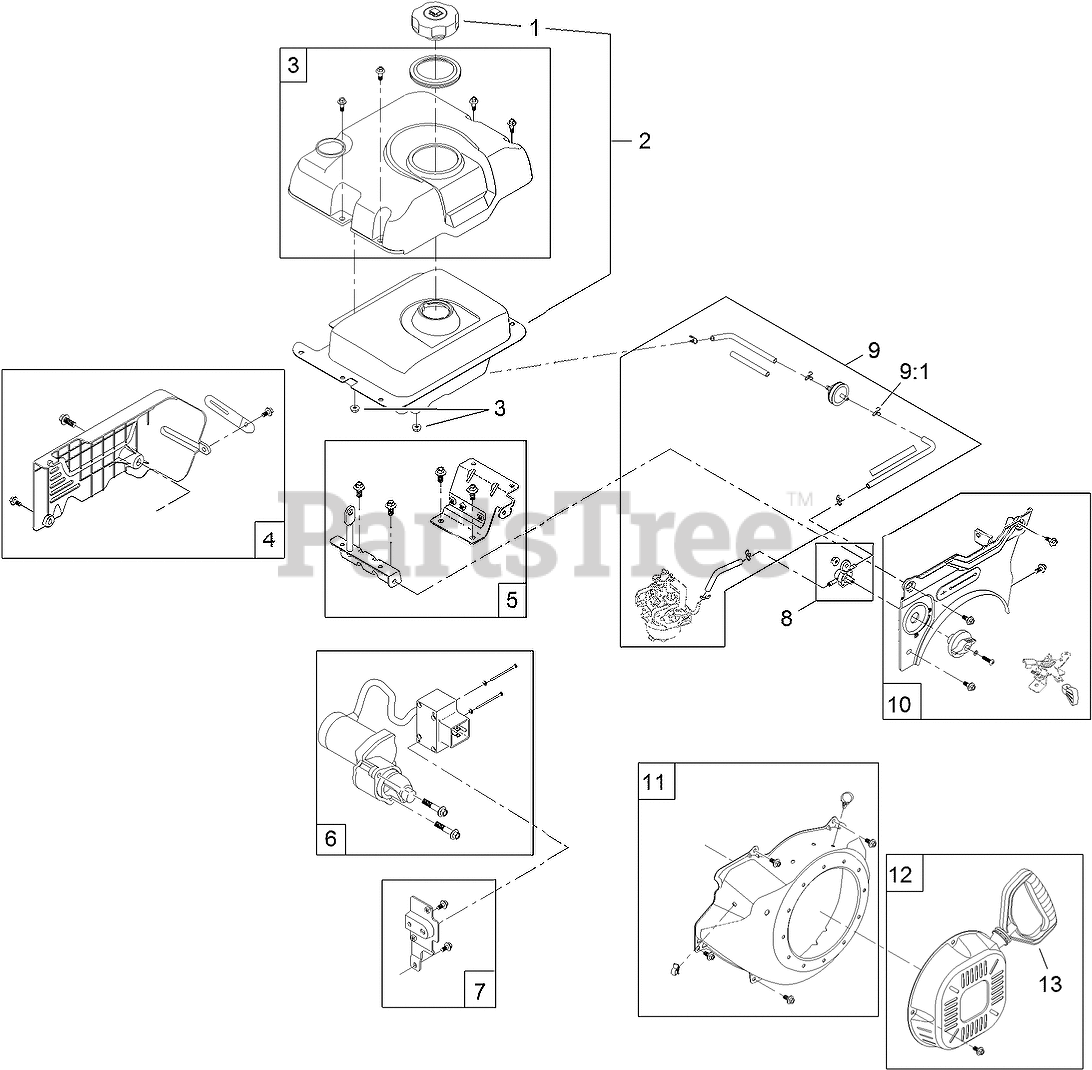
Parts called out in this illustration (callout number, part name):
1	CAP-FUEL
2	FUEL TANK AND CAP KIT
3	FUEL TANK COVER KIT
4	REAR PANEL AND HARDWARE KIT
5	TANK MOUNT BRACKET KIT
6	STARTER KIT
7	SWITCH BOX BRACKET KIT
8	FUEL SHUT-OFF VALVE KIT
9	COMPLETE FUEL LINE KIT
9:1	CLAMP-HOSE
10	FRONT PANEL KIT
11	RECOIL SHROUD KIT
12	RECOIL KIT
13	HANDLE-RECOIL
